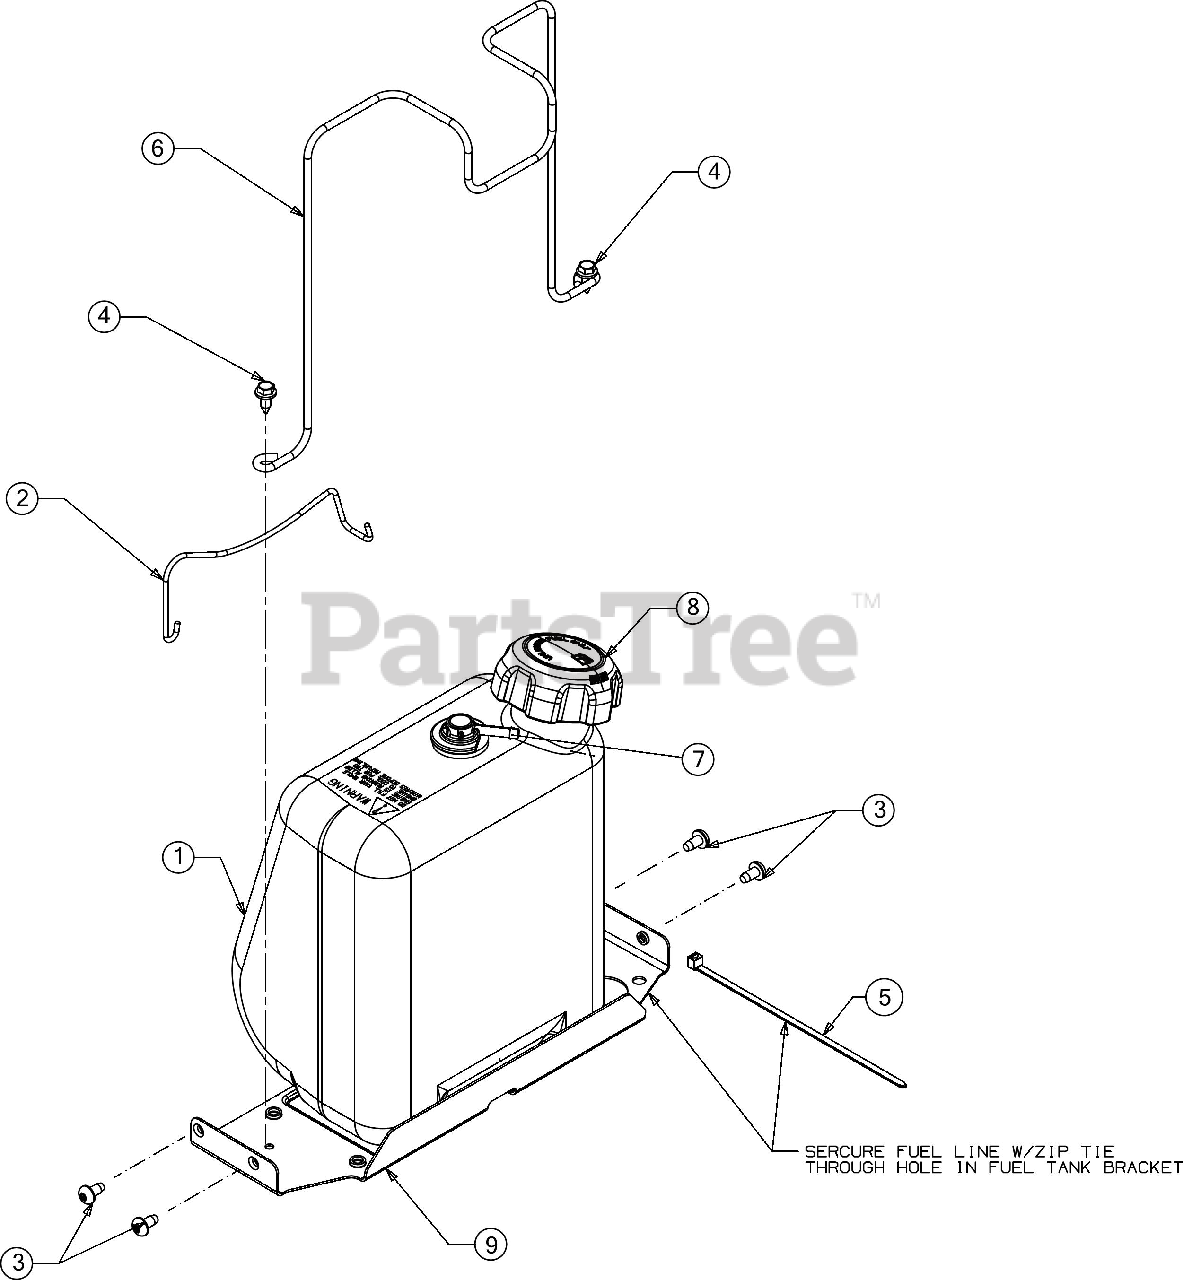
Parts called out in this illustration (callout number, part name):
1	FUEL TANK ASSEMBLY
2	BATTERY ROD ASSEMBLY
3	SCREW 1/4-20 x .5
4	SCREW 1/4-20X.625
5	7" CABLE TIE
6	FUEL TANK SUPPORT ROD -
7	VENT HOSE 3/16 ID
8	FUEL CAP W/TETHER
9	FUEL TANK BRACKET
